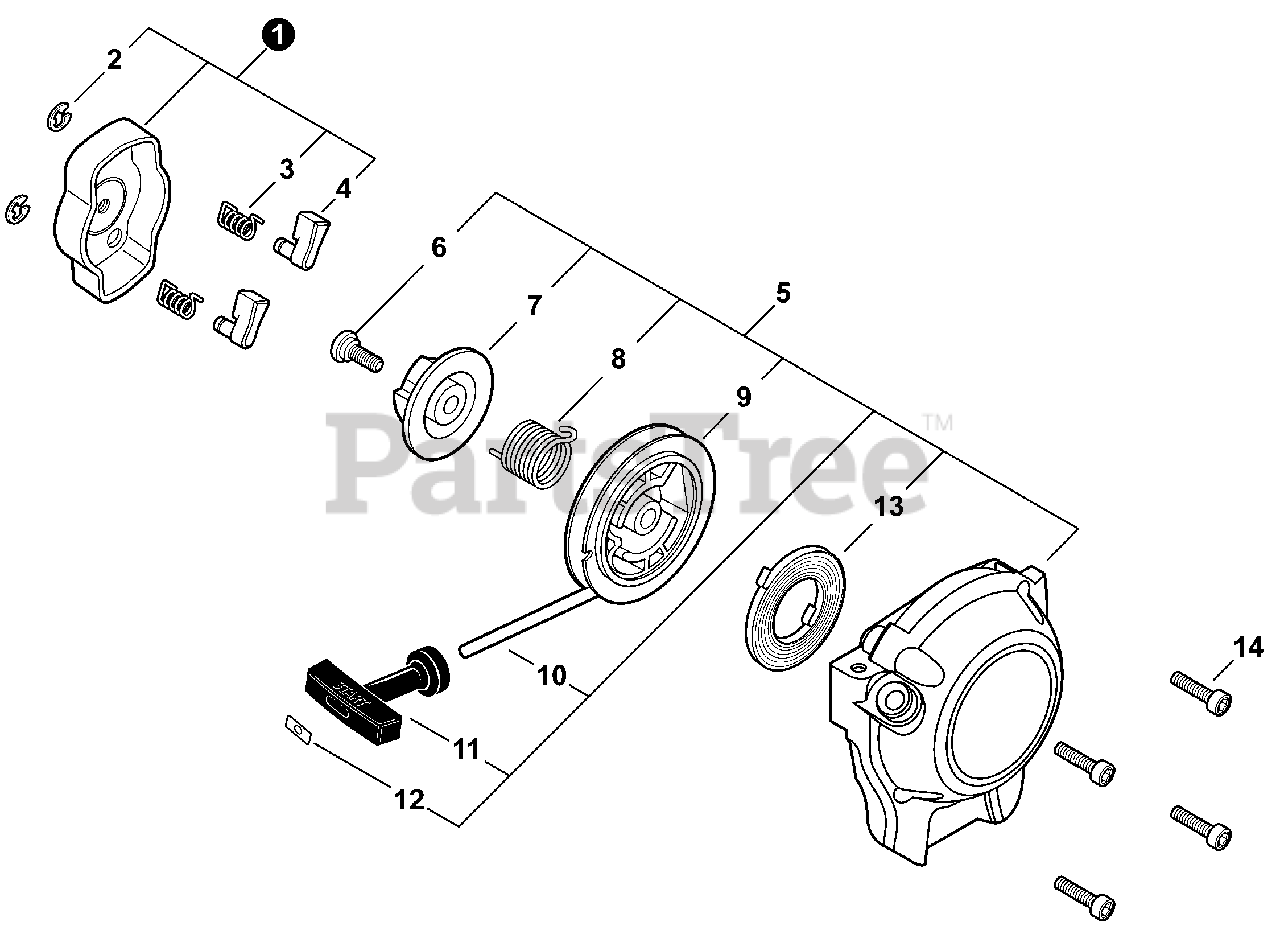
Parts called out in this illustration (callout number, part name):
1	PAWL ASSY, STARTER
2	E-RING 4
3	SPRING, RETURN
4	PAWL, STARTER
5	STARTER ASSY, RECOIL
6	SCREW
7	PLATE, CAM
8	SPRING, TORSION
9	REEL, ROPE
10	ROPE, STARTER
11	GRIP, STARTER
12	RETAINER, ROPE
13	SPRING, RECOIL
14	BOLT, TORX 4×16
